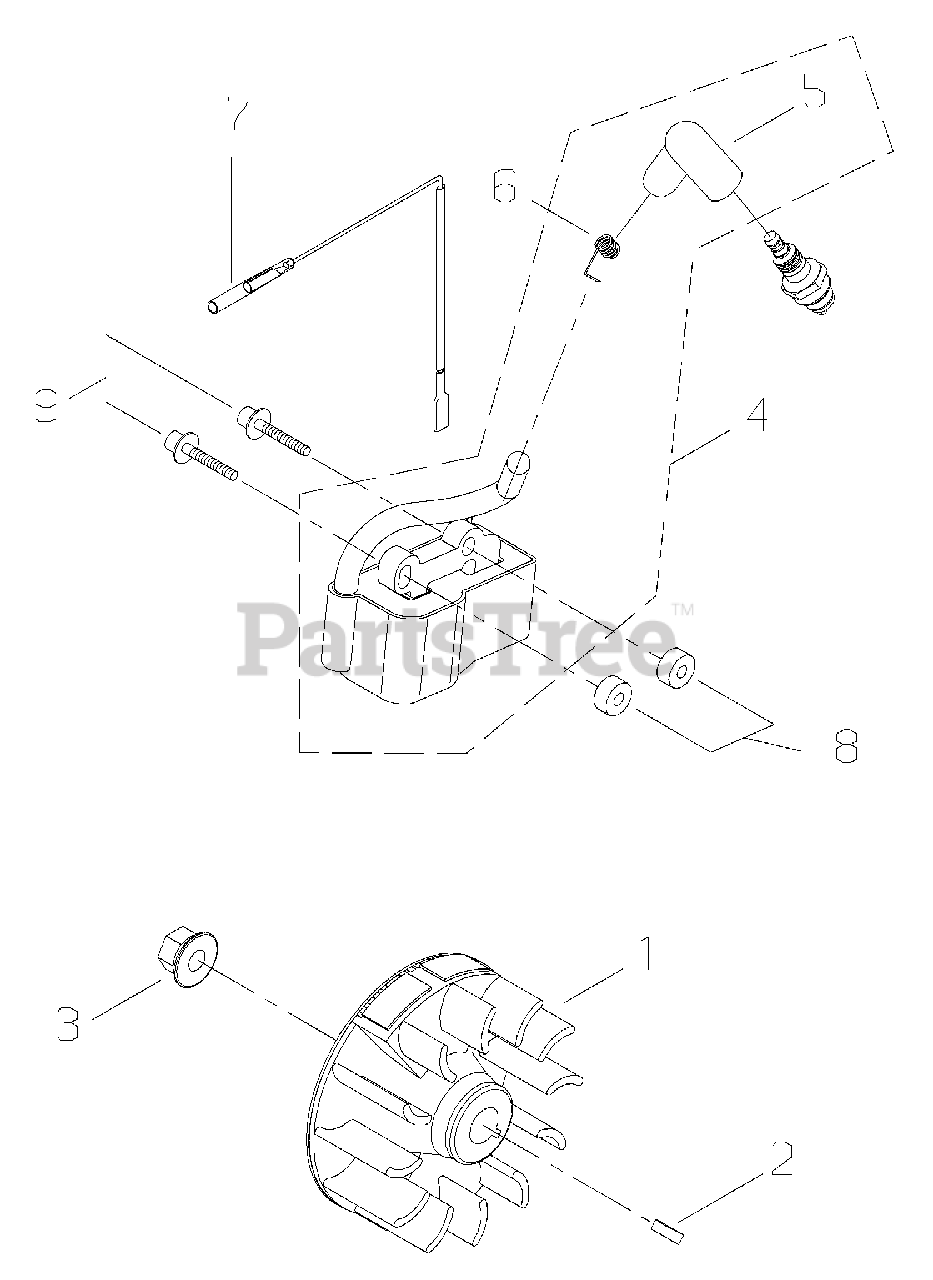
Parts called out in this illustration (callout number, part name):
1	FLYWHEEL
2	KEY - 3X10
3	NUT - 8
4	IGNITION COIL ASSY
5	CAP, SPARK PLUG
6	TERMINAL, SPARK PLUG CAP
7	LEAD - IGNITION
8	INSULATOR
9	SCREW - 4X26
